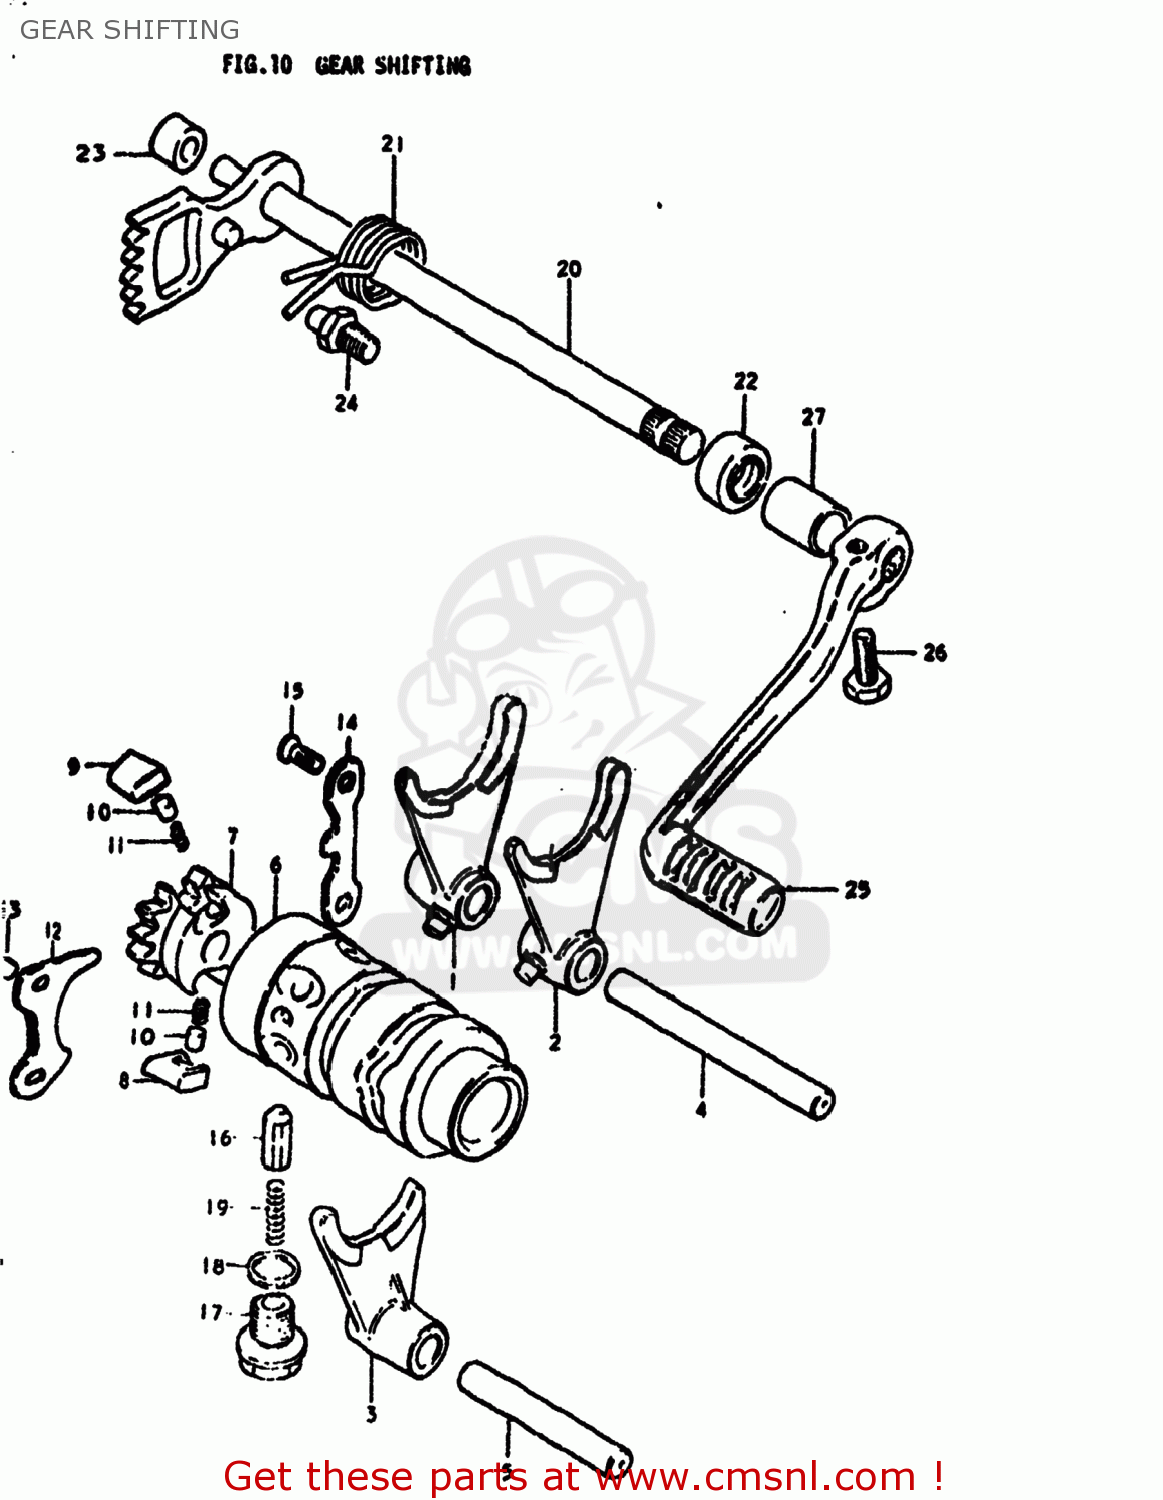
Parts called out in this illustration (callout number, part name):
1	FORK,GEAR SHIFT NO.1
2	FORK,GEAR SHIFT NO.2
3	FORK,GEAR SHIFT NO.3
4	SHAFT,GEAR SHIFT FORK
5	SHAFT,GEAR SHIFT FORK
6	CAM,GEAR SHIFT
7	RETAINER,GEAR SHIFT CAM
8	PAWL,GEAR SHIFT NO.1
9	PAWL,GEAR SHIFT NO.2
10	PIN(5X8)
11	SPRING
12	LIFTER,GEAR SHIFT PAWL
13	SCREW
14	GUIDE,GEAR SHIFT CAM
15	SCREW
16	STOPPER,GEAR SHIFTING
17	BOLT,GEAR SHAFT CAM STOPPER
18	GASKET(14X19.2X2) (NAS)
19	SPRING
20	SHAFT,GEAR SHIFT
21	SPRING
22	OIL SEAL
23	SPACER(12X20X15.3)
24	STOPPER,GEAR SHIFT CAM
25	LEVER,GEAR SHIFT
26	BOLT
27	CUSHION
